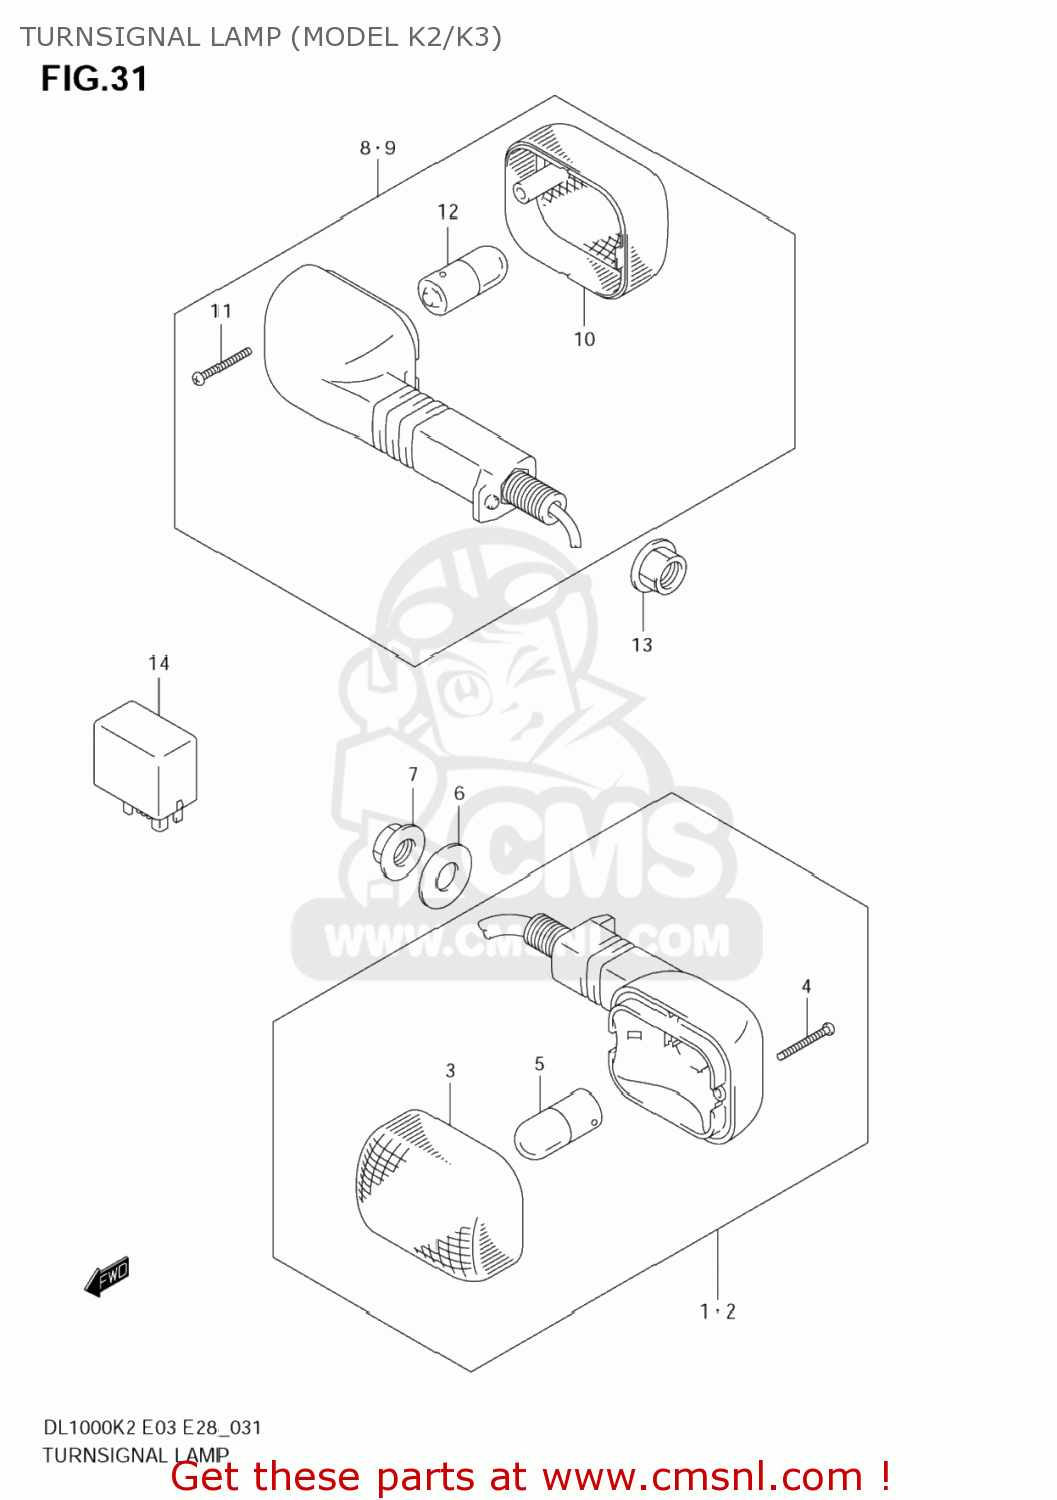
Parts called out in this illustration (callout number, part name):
1	LAMP ASSY,FR TURN SIGNAL,R
2	LAMP ASSY,FR TURN SIGNAL,L
3	LENS
4	SCREW
5	BULB(12V10W)
6	WASHER(12.5X30X1.6)
7	NUT
8	LAMP ASSY,FR TURN SIGNAL,R
9	LAMP ASSY,FR TURN SIGNAL,L
10	LENS
11	SCREW
12	BULB(12V10W)
13	NUT
14	RELAY ASSY,TURNSIGNAL LAMP
